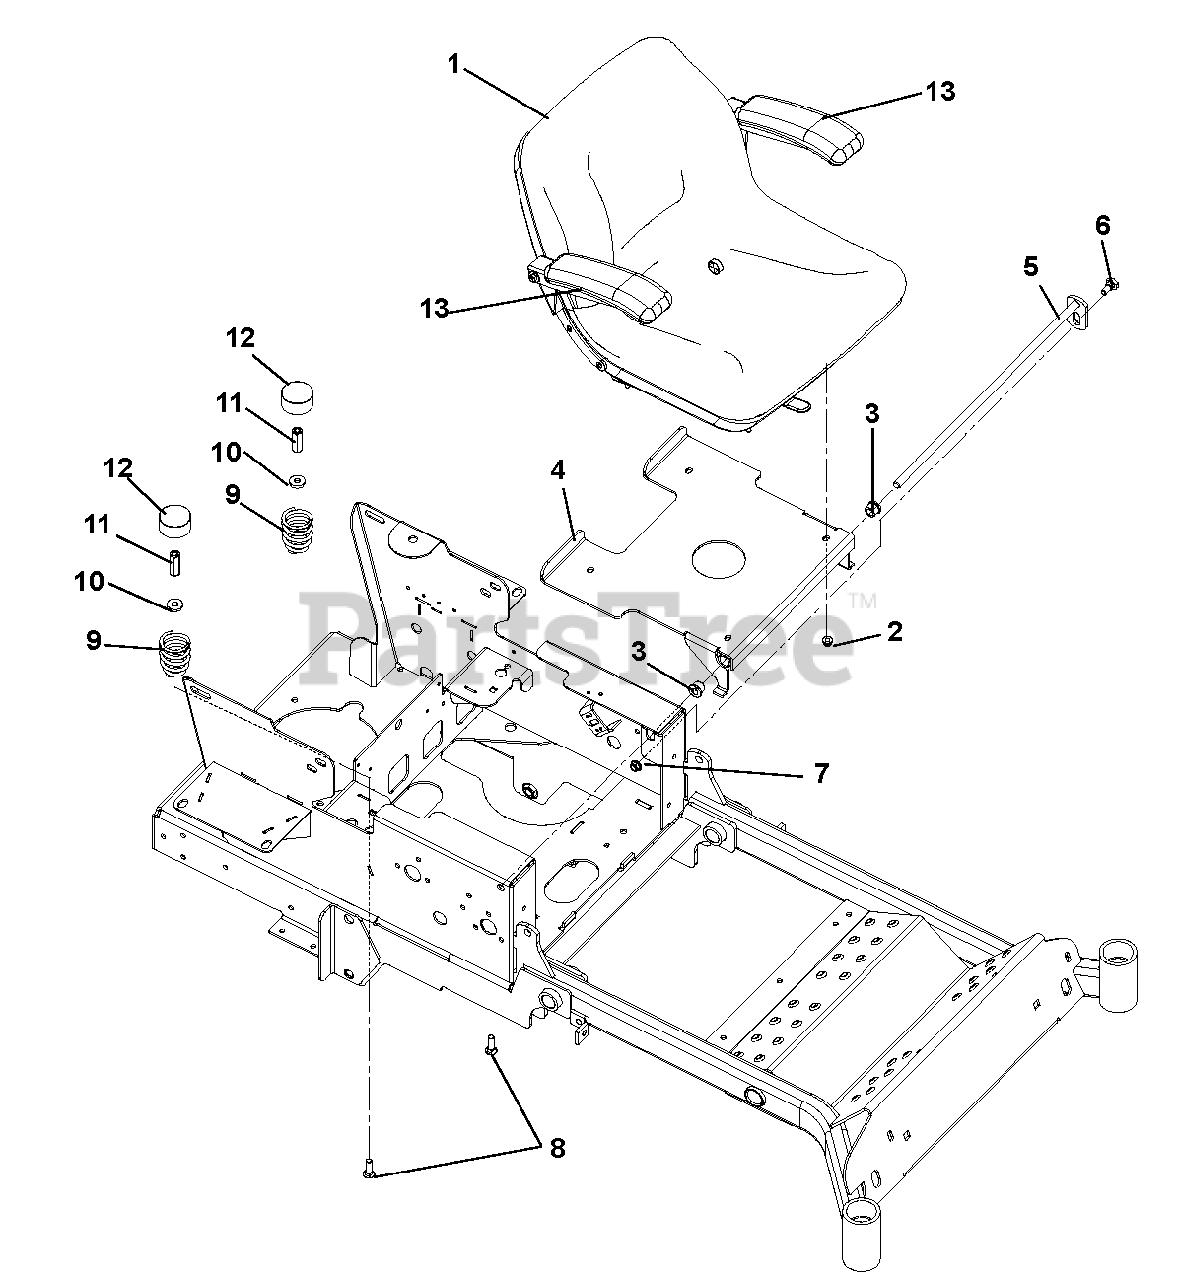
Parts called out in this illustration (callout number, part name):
1	Assembly, Seat with Armrests
2	Nut, Nyloc Flange 5/16-18
3	Bushing, Flange .515 x .750 x .745 x 1.00
4	Weldment, Seat Plate
5	Weldment, Seat Shaft
6	Bolt, Shoulder EP .38-16 x .30 Hex
7	Nut, .38-16 Nyloc Flange
8	Bolt, Round Head Square Neck .38-16 x 1.25 Grade 5
9	Spring, Seat
10	Washer, Flat-Steel .406 x 1.00 x .188
11	Nut, Coupling .375-16 x 1.75
12	Hub Cap
13	Kit, Seat Arm Rests
